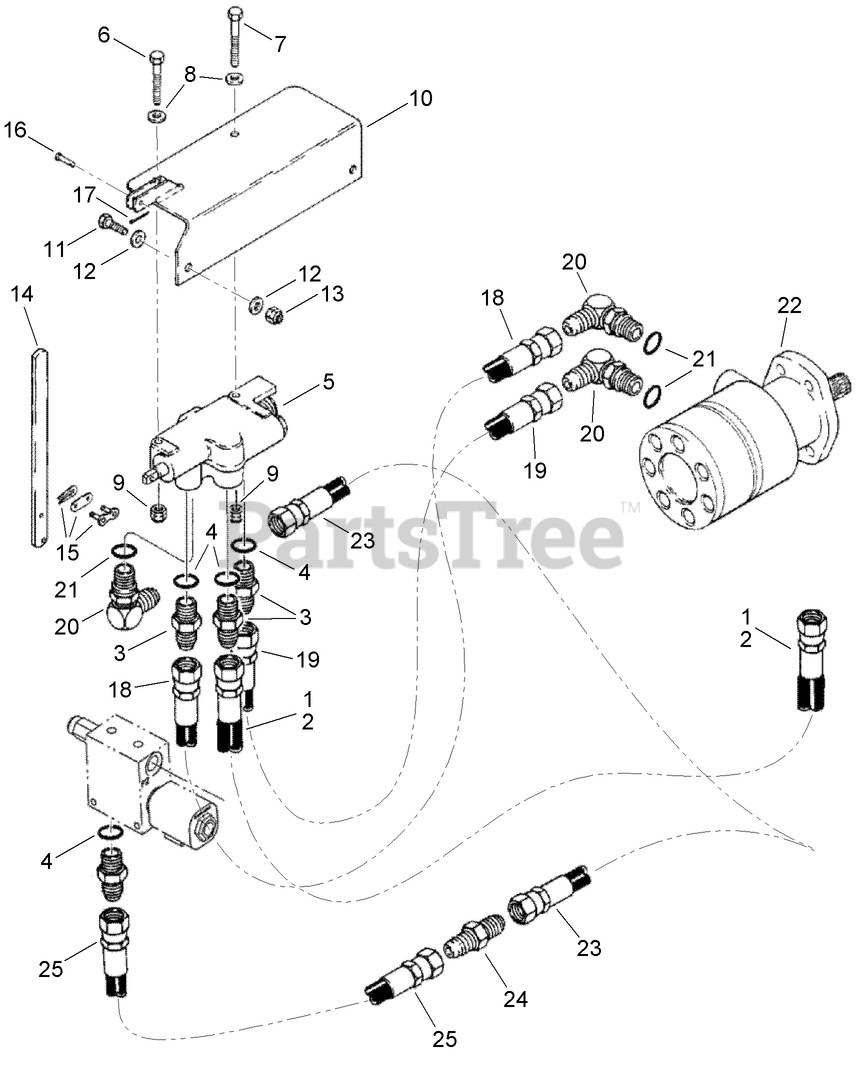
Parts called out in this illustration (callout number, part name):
1	HOSE - 940 mm (37 inch) Long (940 mm) Long, Trencher Control Valve Supply from Plow Double Pump
2	HOSE - 400 mm (15-3/4 inch) Long (400 mm) Long, Trencher Control Valve Outlet to Plow Control Valve
3	CONNECTOR-Str Thd 5/8, 37FL-ORB 5/8
4	O-RING
5	SINGLE SPOOL VALVE ASM
6	BOLT-Hex Hd 5/16 x 2-1/4
8	WASHER-FLAT
9	NUT-HEX
10	BRACKET - Valve Mounting
11	SCREW-HH
12	WASHER-FLAT
13	NUT-HEX
14	LEVER-VALVE
15	LINK-#50, CONNECT (SINGLE PITCH)
16	PIN-CLEVIS
17	PIN - Cotter .062 x .50 in ZND
18	HOSE - 1270 mm (50 inch) Long, Control Valve -A- Port to Motor
19	HOSE-Hydraulic
20	ELBOW-90 Adj 37FL 5/8 Tube
21	O-RING
22	HYD MOTOR ASM
23	HOSE - 400 mm (15-3/4 inch) Long (400 mm) Long, Trencher Control Valve Outlet to Plow Control Valve
24	FITTING-UNION
25	HOSE - 5/8 x 1600
